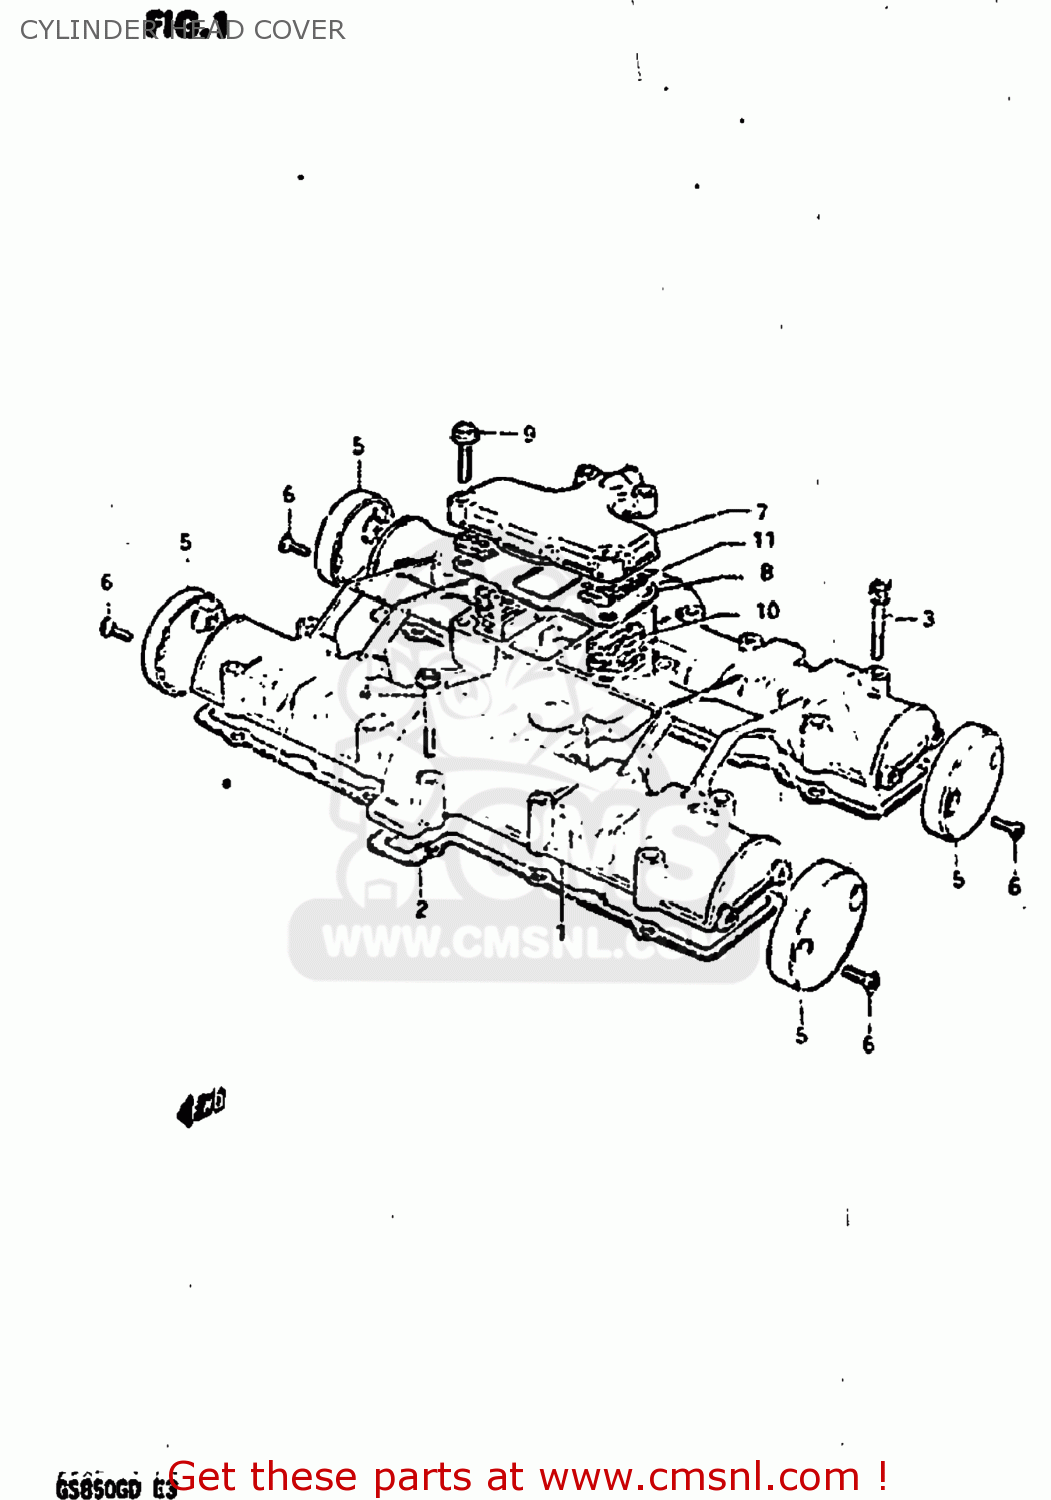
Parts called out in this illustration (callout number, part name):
1	COVER,CYLINDER
2	GASKET,CYLINDER HEAD COVER (MCA)
3	BOLT
4	BOLT,UNDER
5	CAP,CYLINDER HEAD COVER
6	SCREW(5X12)
7	COVER,BREATHER
8	GASKET (MCA)
9	BOLT
10	COVER,BREATHER
11	SEPARATOR,OIL BREATHER
